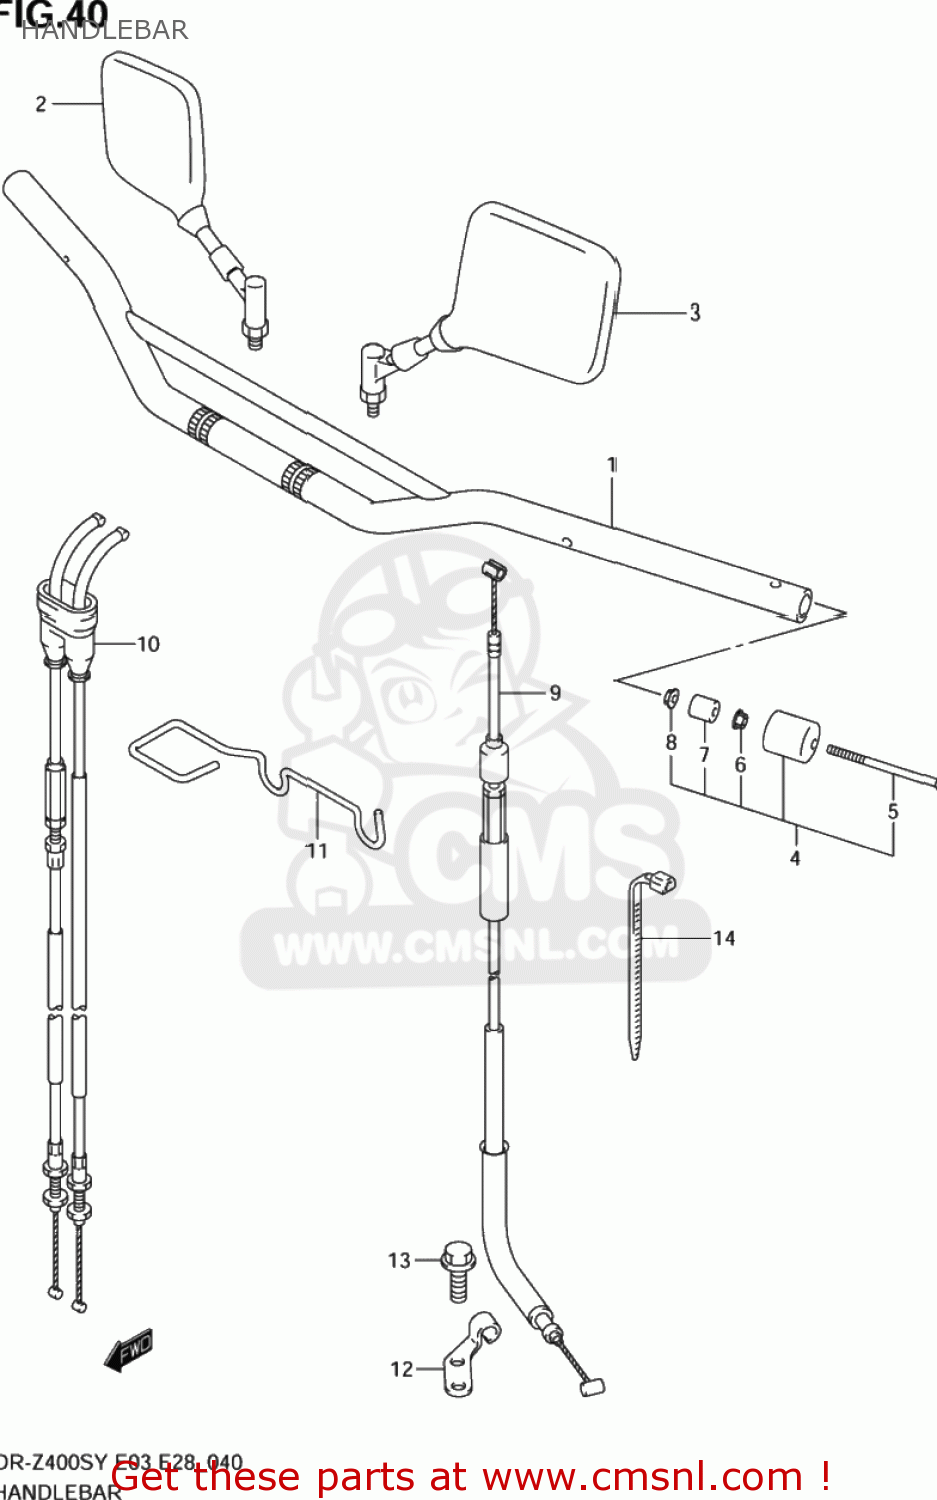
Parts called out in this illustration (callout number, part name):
1	HANDLEBAR(SILVER)
2	MIRROR ASSY,RR VIEW,R
3	MIRROR ASSY,RR VIEW,L
4	BALANCER SET,HANDLEBAR
5	SCREW
6	NUT
7	EXPANDER,HANDLE BALANCER
8	NUT
9	CABLE ASSY,CLUTCH
10	CABLE SET,THROTTLE
11	GUIDE,THROTTLE CABLE
12	STOPPER,CLUTCH CABLE
13	BOLT(6X15)
14	CLAMP(L:145)
